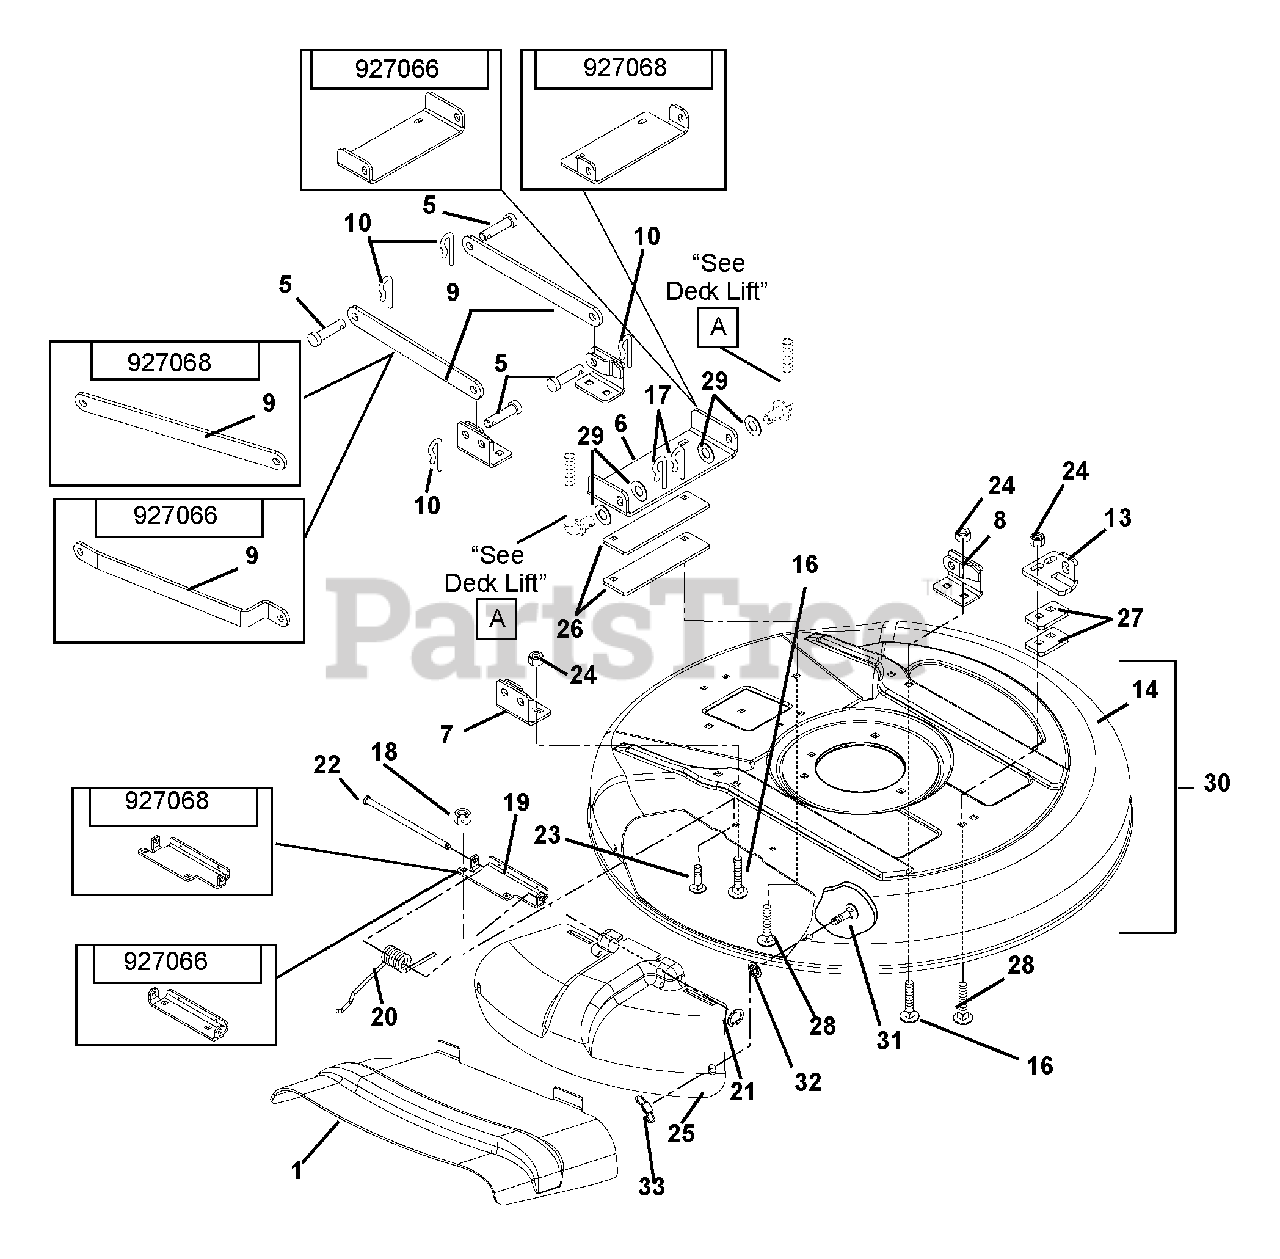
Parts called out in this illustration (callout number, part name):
1	Discharge Chute
2	Key, Square .25 x .38 x .25
3	Bearing, Slinger
4	Bearing, Ball 1.00 x 2.00 x .56
5	Pin, Clevis .494 x 1.00
6	Bracket, Rear Hanger 28" (066)
6	Bracket, Rear Hanger 32" (068)
7	Bracket, Deck Link Right Hand (066)
7	Bracket, Deck Link Right Hand (068)
8	Weldment, Deck Link Right Hand (066)
8	Weldment, Deck Link Left Hand (068)
9	Stabilizer , 28" Deck (Right Hand Only)(066)
9	Link Stabilizer (066)
9	Link Stabilizer (068
10	Clip, Spring
11	Assembly, Spindle Housing
12	Spacer, 1.00 x 1.25 x 1.60
13	Bracket, Front Lift Hanger (066)
13	Bracket, Front Lift Hanger (068)
14	Deck, 28" (066)
14	Deck, 32" (068)
15	Shaft, 32" Input
16	Bolt, Round Head Square Neck .38-16 x .75 Grade 5
17	Pin, Hair External- #11
18	Nut, Locking Center .25-20
19	Bracket, 28" Mulch Cover Hinge
19	Bracket, 32" Mulch Cover Hinge
20	Spring, Torsion
21	Ring, Retaining External .312 x .025
22	Rod, Hinge
23	Bolt, Round Head Square Neck .25-20 x .75 Grade 5
24	Nut, Locking Top Flange .38-16
25	Cover, 28" Deck Mulch
25	Cover, 32" Deck Mulch
26	Plate, 32" Deck Spacer
27	Plate, 32 Deck Front Hanger
28	Bolt, Round Head Square Neck .38-16 x 1.25
29	Washer, Flat Steel .518 x 2.00 x .105
30	Kit, 28" Deck Assembly Service (066)
30	Kit, 32" Deck Assembly Service (068)
31	Bolt, Round Head Square Neck .31-18 x .75 Grade 2
32	Nut, Push .312
33	Nut, Nylock Wing .312-18
